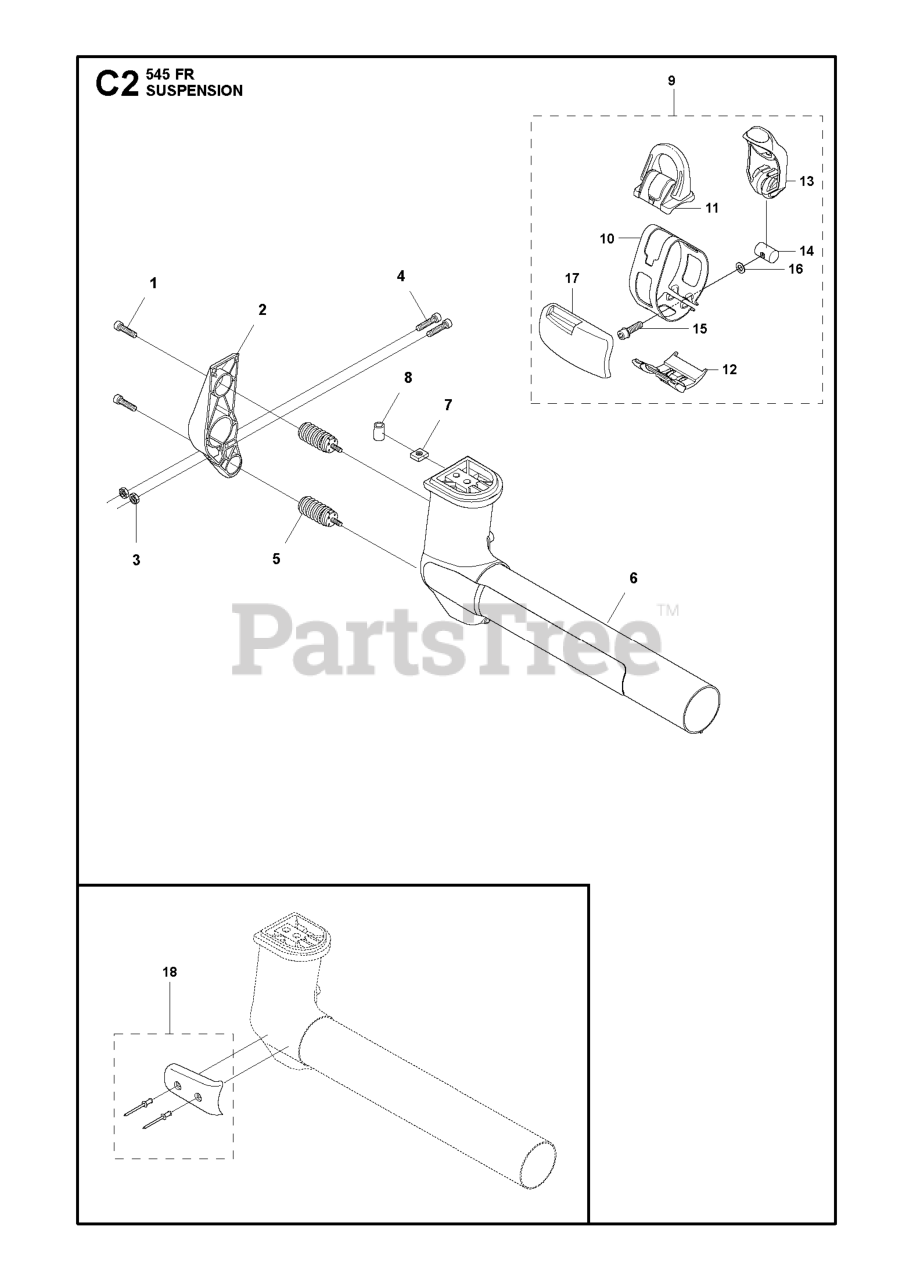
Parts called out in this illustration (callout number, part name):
2	HOLDER ANTIVIBRATION
5	ANTIVIBRATION ELEMENT ASSY
6	SUSPENSION HUSQVARNA
12	GUIDE RAIL
16	WASHER 5.3X12
17	WEAR PROTECTION
18	WEAR PLATE ASSY
